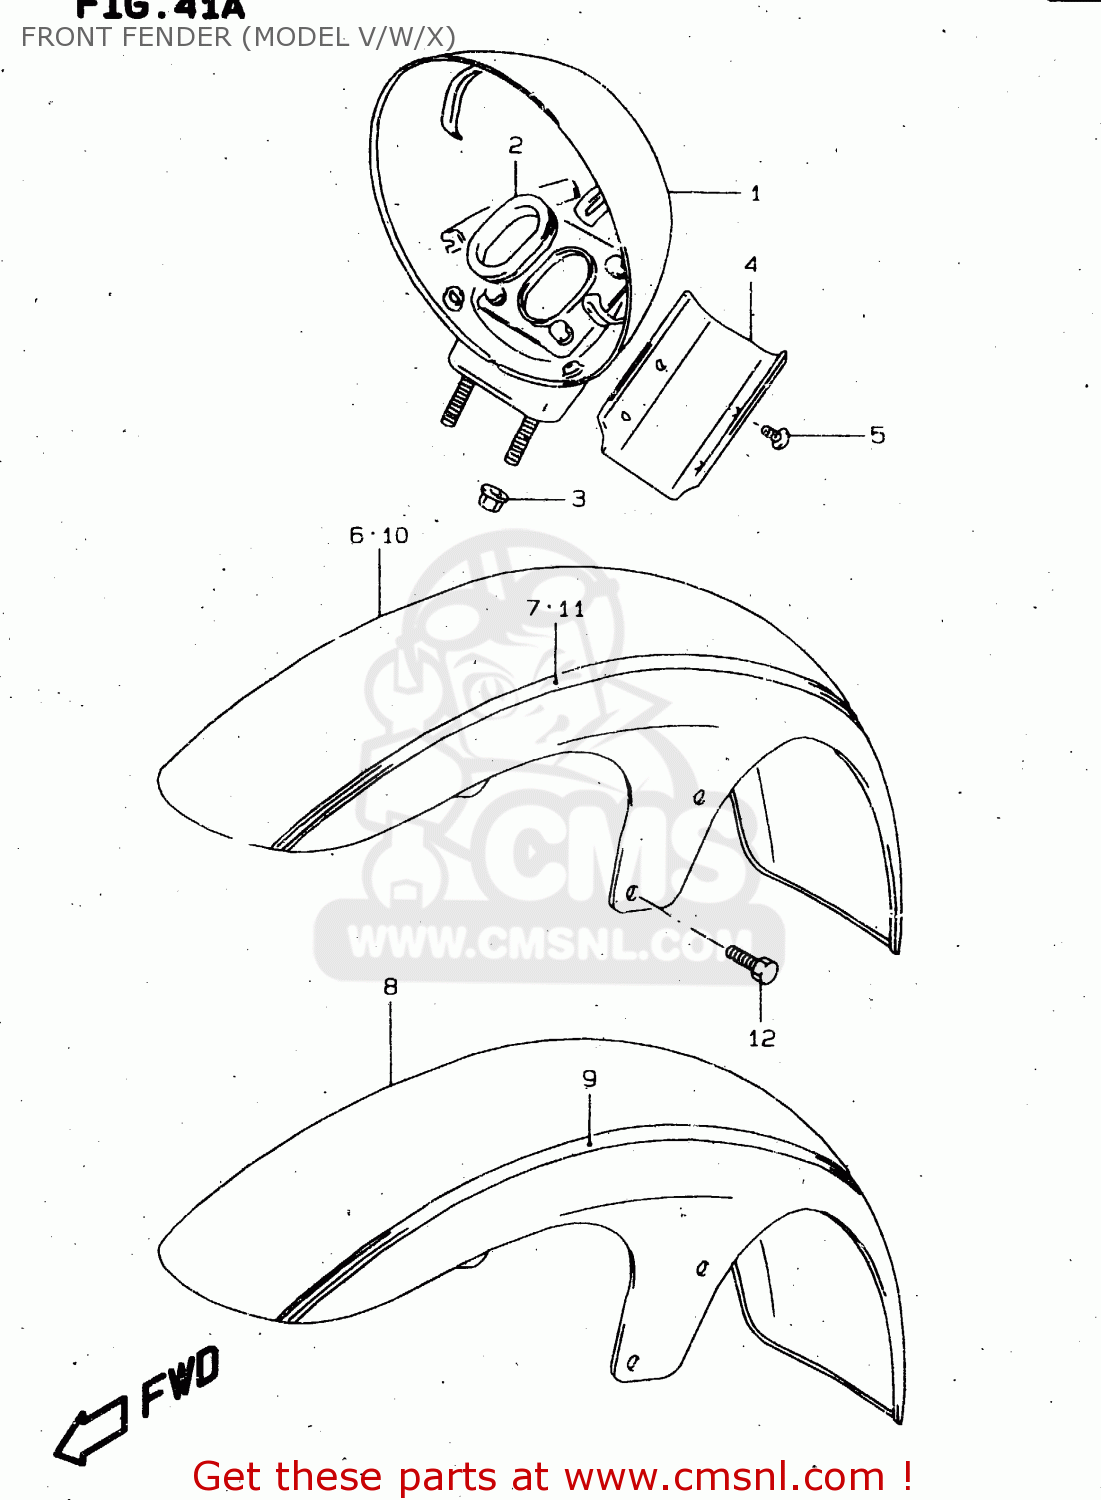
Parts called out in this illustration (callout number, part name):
1	HOUSING,HEADLAMP
2	GROMMET
3	NUT
4	COVER,HEADLAMP HSG
5	SCREW
6	FENDER, FRONT
7	TAPE SET,FRONT FENDER
8	FENDER, FRONT
9	TAPE SET,FRONT FENDER
10	FENDER, FRONT
11	TAPE SET,FR FENDER STRIPING
12	BOLT
